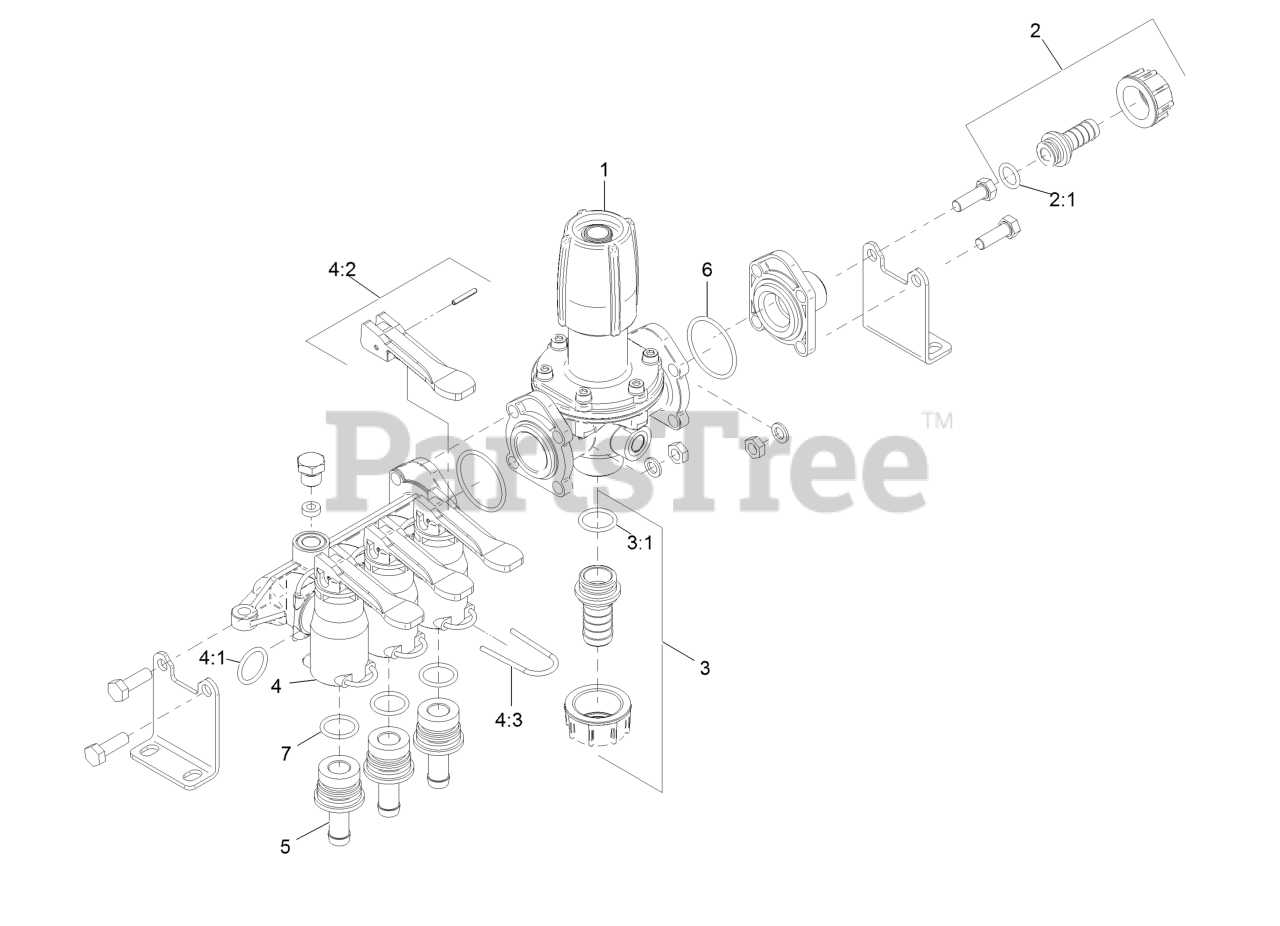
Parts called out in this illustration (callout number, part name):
1	Regulator
2	Flynut Assembly
2:1	O-Ring Kit, Regulator Inlet Barb
3	Flynut Assembly
3:1	O-Ring Kit, Regulator Outlet Barb
4	Valve Assembly W/ O-Ring
4:1	O-Ring Kit, Valve Inlet
4:2	Lever And Pin Assembly
4:3	Wireform Retainer Kit
5	Hose Barb
6	O-Ring Kit, Regulator Flange
7	O-Ring Kit, Valve Outlet Barb
